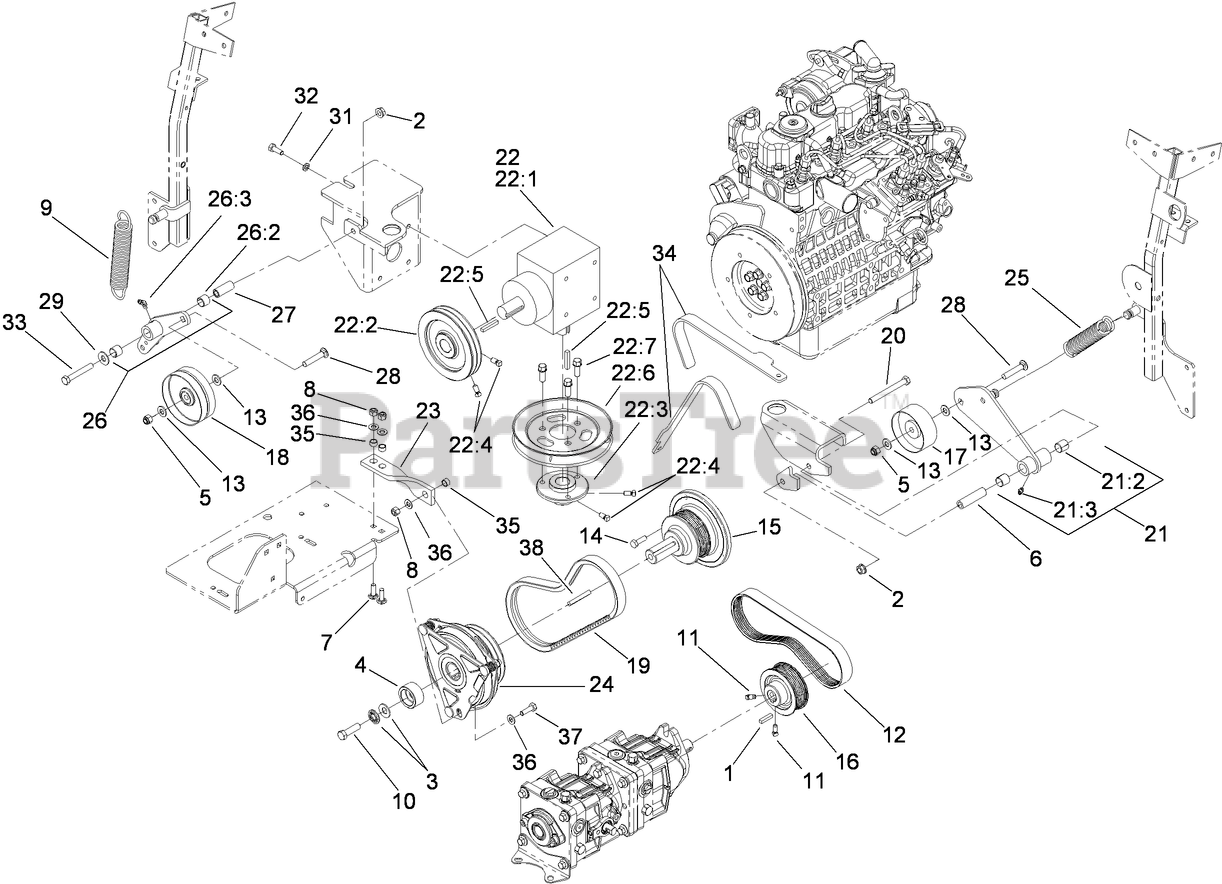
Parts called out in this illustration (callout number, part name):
2	NUT-HHF, WHIZ
3	WASHER-SPRING
4	RETAINER-CLUTCH
5	NUT-LOCK, NI
6	BUSHING-PIVOT, IDLER
7	SCREW-CARR
8	NUT-LOCK, NI
9	SPRING-EXTENSION
10	SCREW-HH
11	SCREW-SET
12	BELT-V
13	WASHER-FLAT
14	SCREW-HH
15	SHAFT-STUB
16	PULLEY
17	PULLEY-FLAT
18	PULLEY-FLAT
19	BELT-V
20	SCREW-HH
21	PUMP IDLER ARM ASM
21:2	SLEEVE-BEARING
21:3	FITTING-GREASE
22	GEARBOX ASM
22:1	GEARBOX-90 DEG
22:2	PULLEY
22:3	HUB-PULLEY
22:4	SCREW-SET
22:5	KEY-SQUARE
22:6	PULLEY-B SECTION
22:7	SCREW-HWH
23	STRAP-STOP, CLUTCH
24	CLUTCH-MAGNETIC
25	SPRING-EXTENSION
26	GEARBOX IDLER ASM (W/BEARINGS)
26:2	SLEEVE-BEARING
26:3	FITTING-GREASE
27	BUSHING
28	SCREW-CARR
29	WASHER-FLAT
31	WASHER-LOCK
32	SCREW-HH
33	SCREW-HH
34	TOOL-ALIGNMENT, PULLEY
35	SPACER
36	WASHER-PLAIN
37	SCREW-HH
38	KEY-SQUARE
